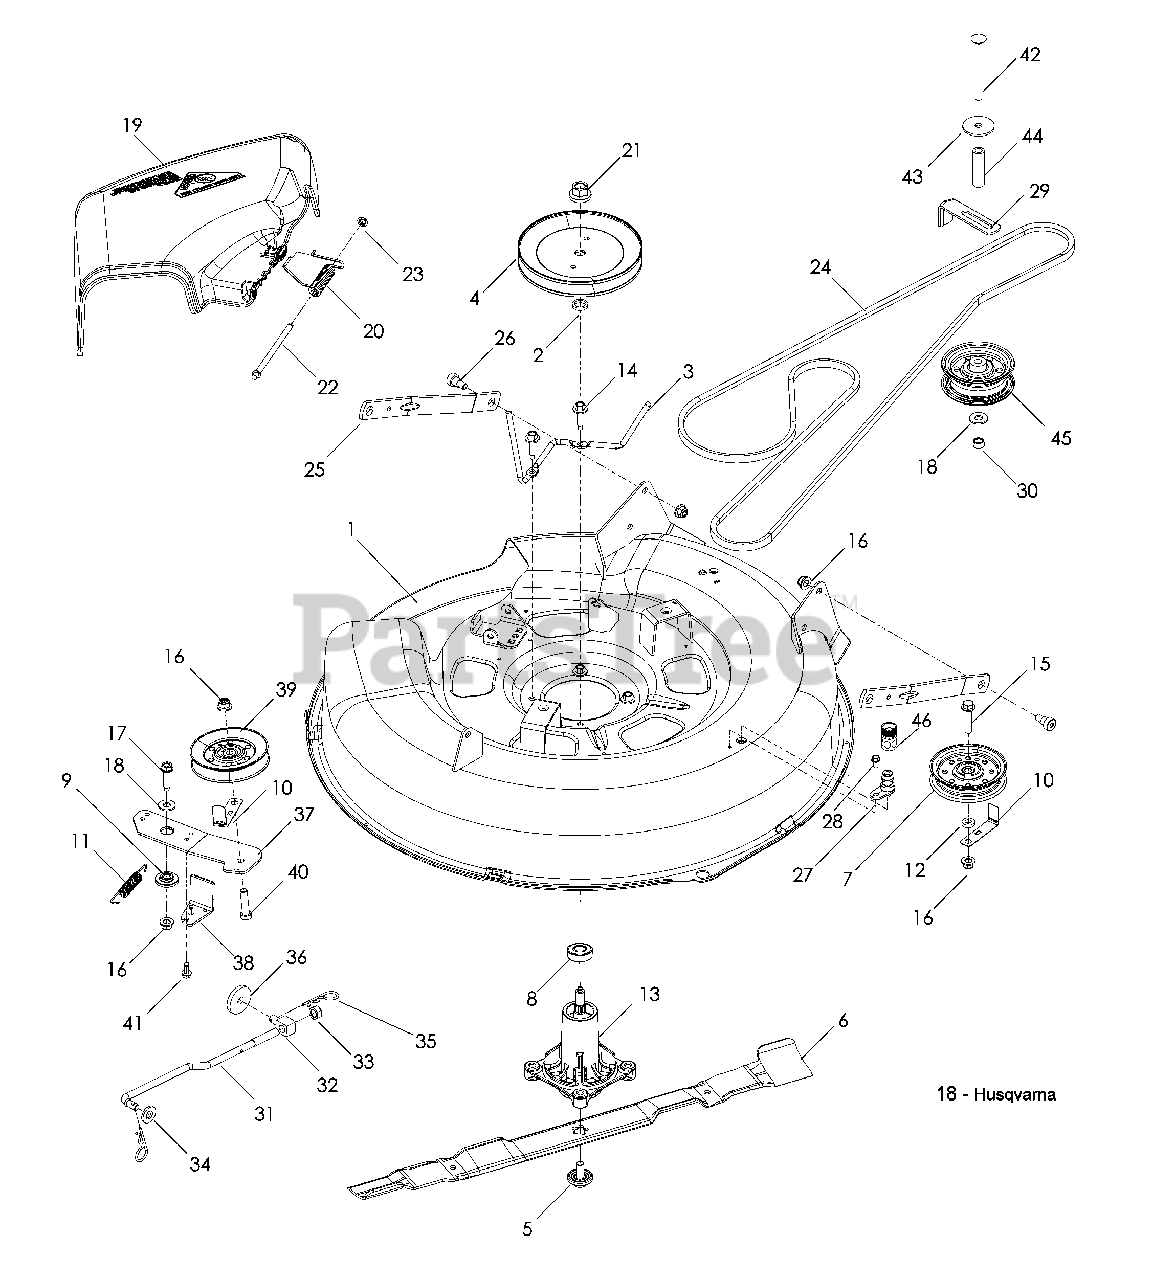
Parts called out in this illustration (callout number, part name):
1	DECK w/ DECALS
2	WASHER/SPACER
3	KEEPER, BELT
4	PULLEY, MANDREL
5	BOLT/WASHER ASSM
6	BLADE MOWER/MULCH
7	PULLEY, IDLER
8	BEARING, BALL
9	SPACER RETAINER
10	KEEPER, BELT
11	SPRING RETURN
12	WASHER 3/8 x ¾
13	MANDREL ASSM
14	SCREW 5/16-18 WASHER HD
15	BOLT 3/8-16 x 1 ¾ WHIZLK
16	NUT 3/8-16 FLANGE NYLOC
17	BOLT 3/8-16 x 1½ THD FRM
18	WASHER 3/8 FLAT STD
19	CHUTE, DISCHARGE
20	SPRING, TORSION
21	NUT 9/16 TOP CENTER LOCK
22	ROD, HINGE
23	NUT 5/ PUSH
24	BELT, DECK
25	ARM, DECK SUSPENSION
26	BOLT 3/8-16 x 3/8 SKT HD
27	WASHOUT PORT
28	BOLT ¼-20 x ½ HWST
29	GUIDE, BELT
30	NUT 3/8-16 HEX NYLOC
31	LINK, SUSPENSION
33	NUT 7/16-14 HEX NYLOC
34	WASHER ½ SAE
36	WASHER 1¾ x ¼ HEAVY
37	ARM, IDLER
38	ARM, LH BRAKE
39	IDLER V-GROOVE
40	HCS 3/8-16 x 1½
41	SCREW ¼-20 x 5/8 THDROLL
42	RHSNB 3/8-16 x 4
43	WASHER 3/8 SPECIAL
44	SPACER .390 ID x 2¼
45	PULLEY, DECK IDLER
46	COUPLING, QUICK DISC
